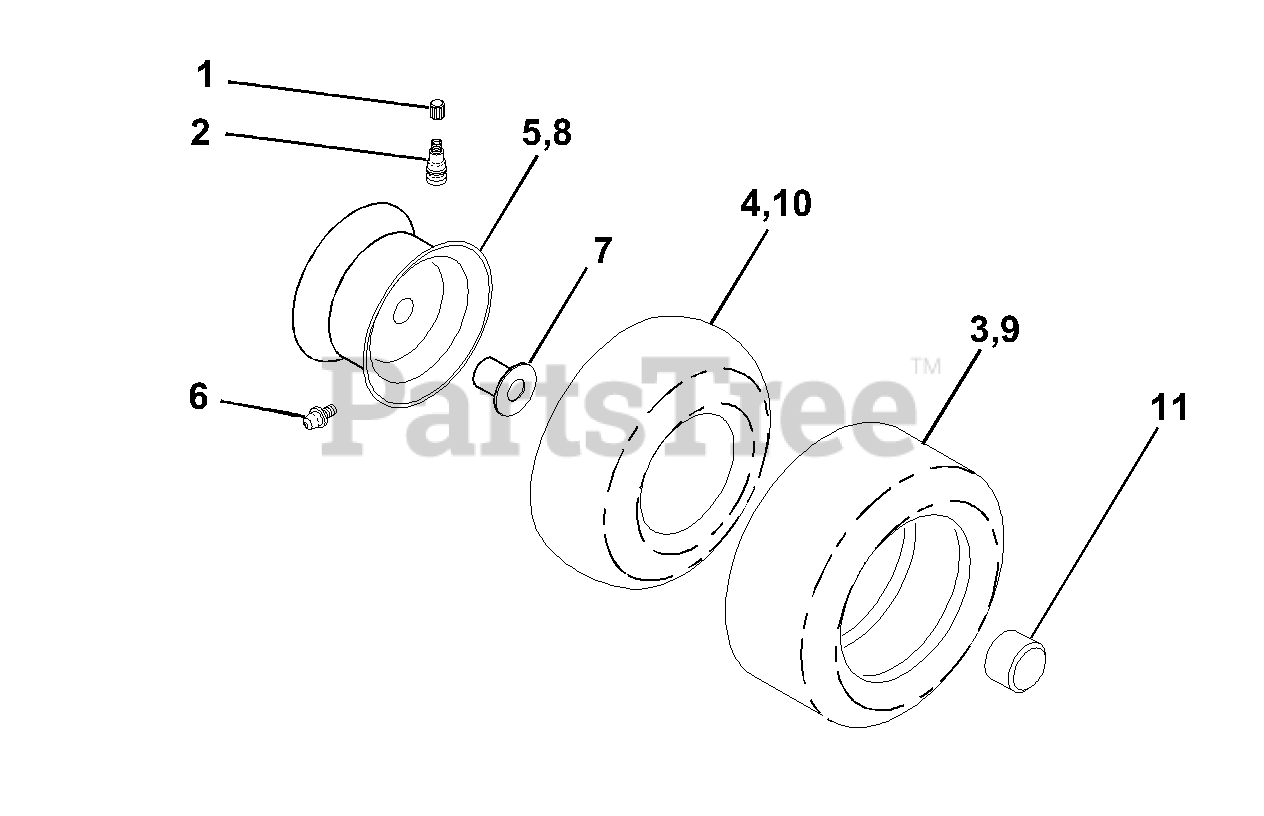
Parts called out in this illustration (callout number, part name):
1	Cap Valve Tire
2	Stem Valve
3	Tire F Ts 15 X 6 0 - 6 Service
4	Tube Front
5	Rim Asm 6"front Service
6	Fitting Grease
7	Bearing Flange
8	Rim Asm 8"rear Service
9	Tire R Ts 20x10-8 C Service
10	Tube Rear
11	Cap Axle Blk 1 50 X 1 00
